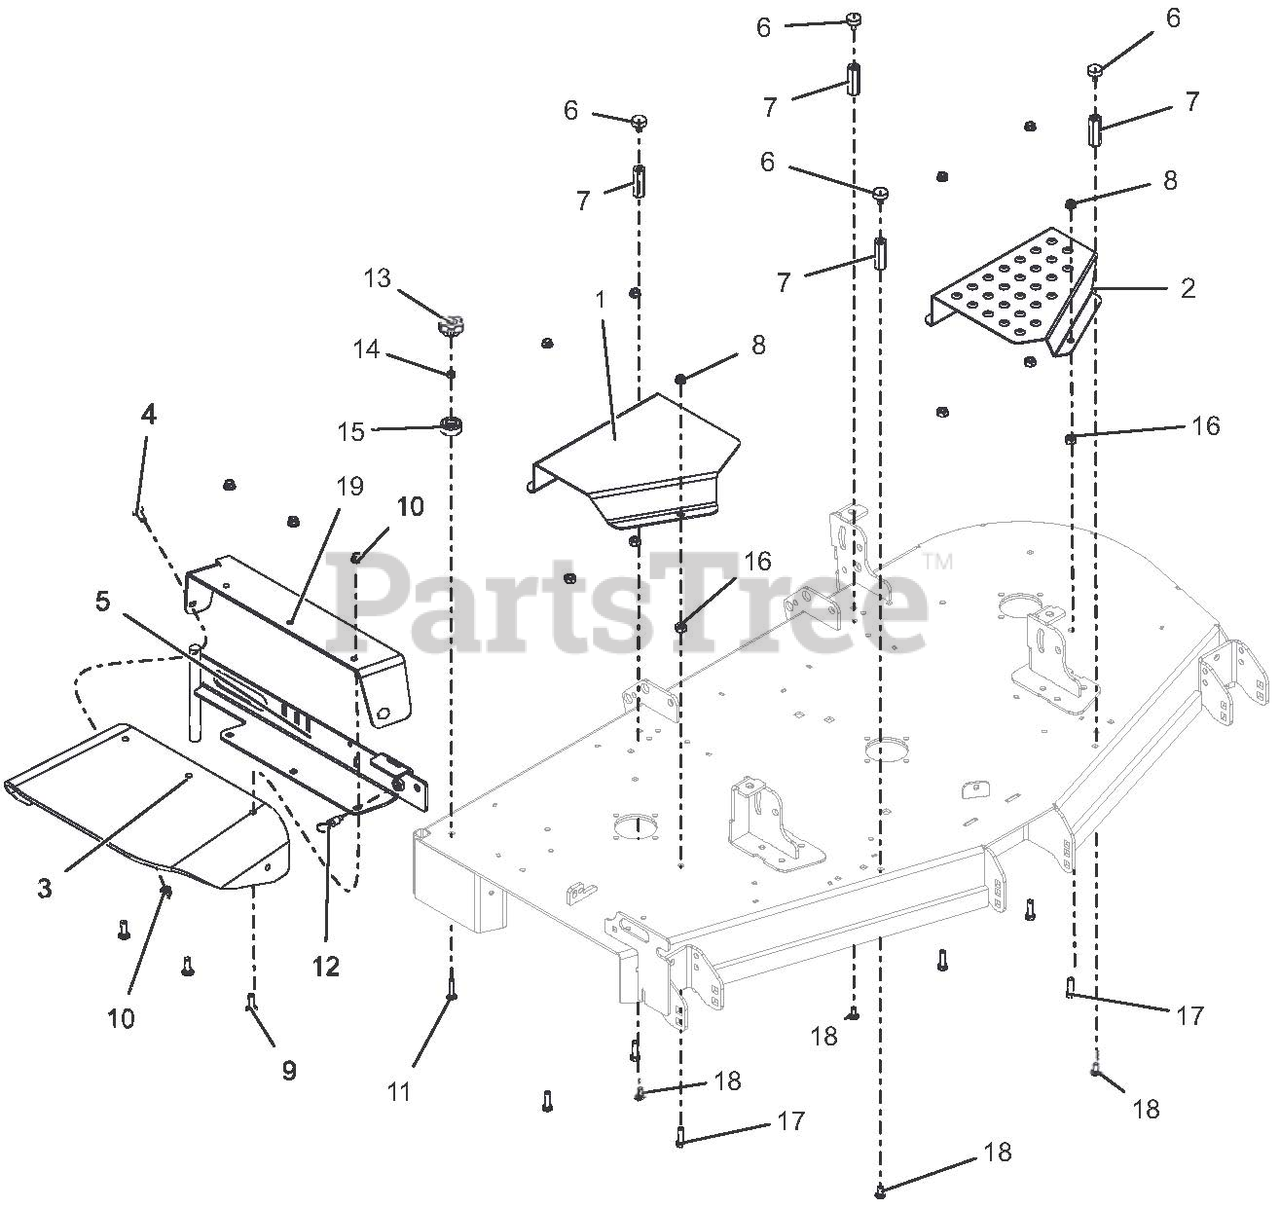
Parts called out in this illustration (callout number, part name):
1	GUARD, 60"-66" RH DECK BELT-BLACK
2	GUARD, 60" LH DECK BELT-BLACK
3	CHUTE, RUBBER DISCHARGE
4	BLT-RDHDSQNK .38-16X1.00 G5 YWZC
5	WLDMT, 52"-60" DISCH CHUTE MTG-RED
6	BUMPER, RUBBER
7	NUT, .31-18 X 2.25 LG COUPLING
8	@NUT-SPNLK-FLG .375-16 YWZC
9	BLT-RDHDSQNK .38-16X1.25 G5 YWZC
10	NUT-LK-NYL-FLG .38-16 YWZC
11	BLT-RDHDSQNK .31-18X1.50 G5 YWZC
12	PULL PIN,.50-13THDX.310 PLNGR
13	KNOB, CLAMPING
14	NUT-LK-CTR .31-18 YWZC
15	BUMPER, RECESSED 1.50 X .63 W/.31 HOLE
16	NUT-HEAVY HEX .38-16 YWZC
17	BLT-HEX .38-16X1.25 GR5 YWZC
18	BLT, RDHDSQNK .31-18X.75 LOCTITE
19	DISCHARGE CHUTE SUPPORT W/SAFETY DECAL-RED
